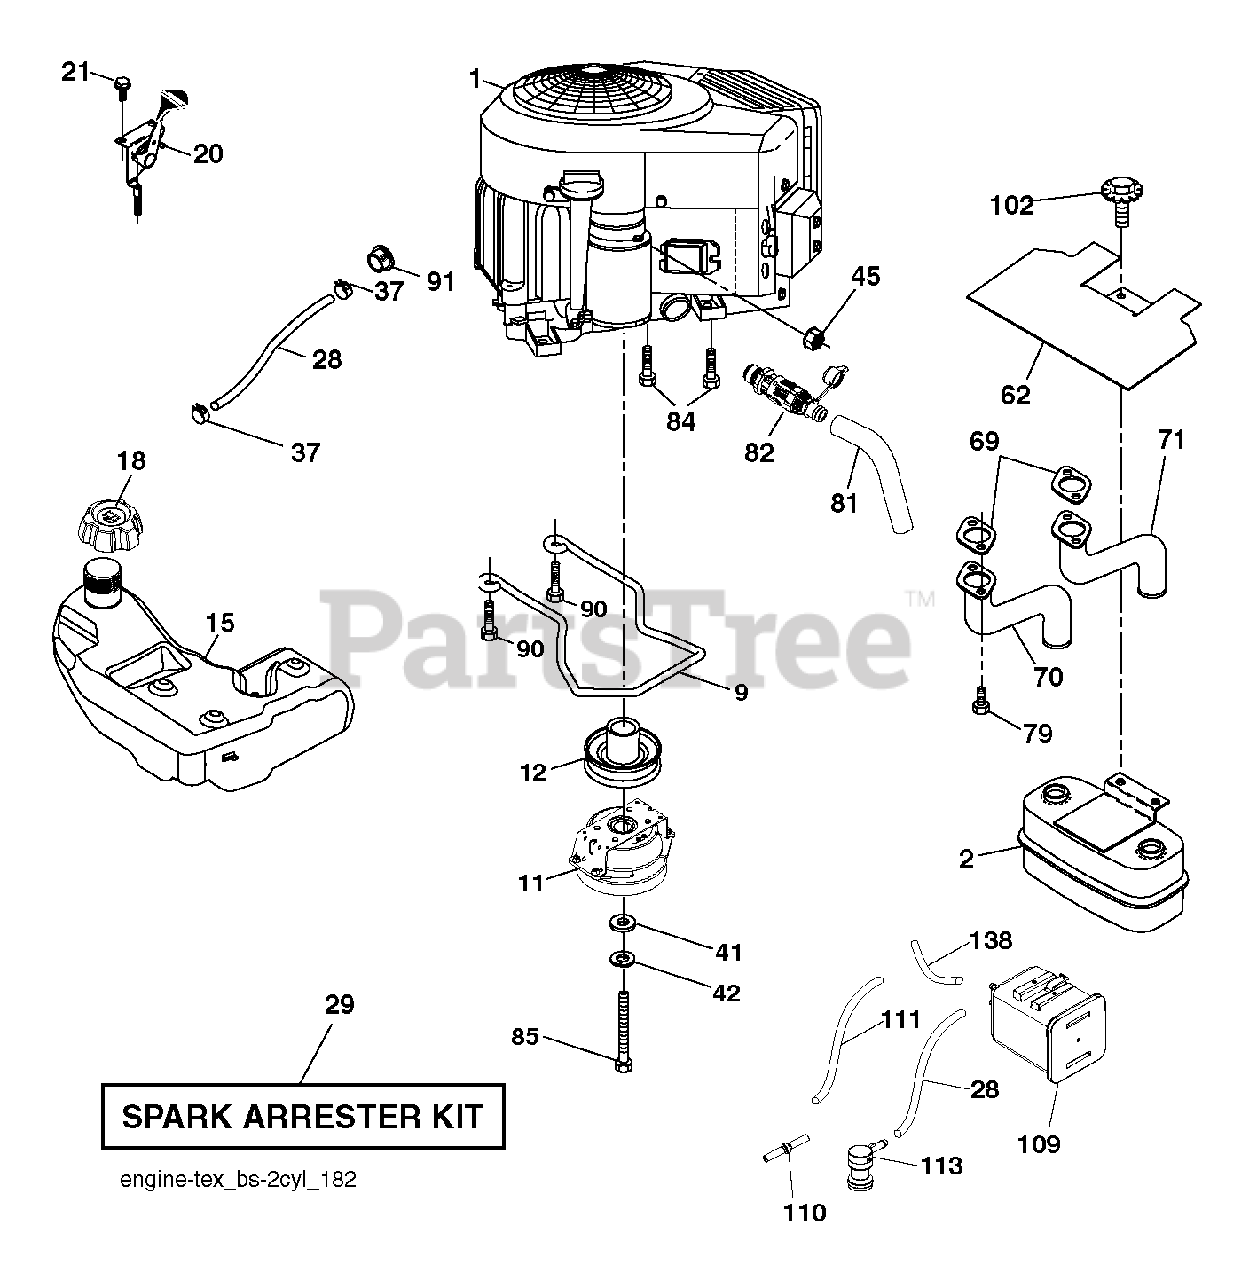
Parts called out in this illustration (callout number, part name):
2	Muffler Assembly, Twin MN
9	KEEPER.BELT.ENG.4.25"2.BLT.431
11	CLUTCH.OGURA.5.0PD.GT1.5A-EH07
12	PULLEY.ENGINE.TUFFTORQ
15	Fuel Assembly Tank, 3 Gallon
18	CAP ASSY FUEL 3" GRAY
20	THROTTLE.COBRA.38"READSTART.BK
21	SCREW.#10 X 0.750.BOS
28	LINE.FUEL.20"FRONT.EMI
29	KIT.SPARK ARRESTOR 794945 B&S
37	HOSE CLAMP
42	WASHER 7/16 LOCK
45	NUT
62	SHIELD.HEAT.MUFFLER
69	GASKET.MUFFLER
70	EXHAUST.TUBE.LH.BS/TWIN
71	EXHAUST.TUBE.RH.B&S.TWIN.INTEK
79	SCREW.SOCKET.HEAD.5/16-18
81	TUBE, DRAIN OIL ASM.
82	VALUE.OIL.DRAIN
84	SCREW.3/8-16
85	BOLT.HEX.7/16-20X3.75.GR5.RED
90	SCREW 3/8-16X1
91	BUSHING.1.375OD
102	SCREW
109	CANNISTER, CARBON
110	VALVE.ASM.ANTI-SLOSH
111	RP PURGE LINE
113	VALVE.SLANT.CARTRDG.90 DEG.TEX
138	PURGE.LINE.36"REAR.CALIFORNIA
